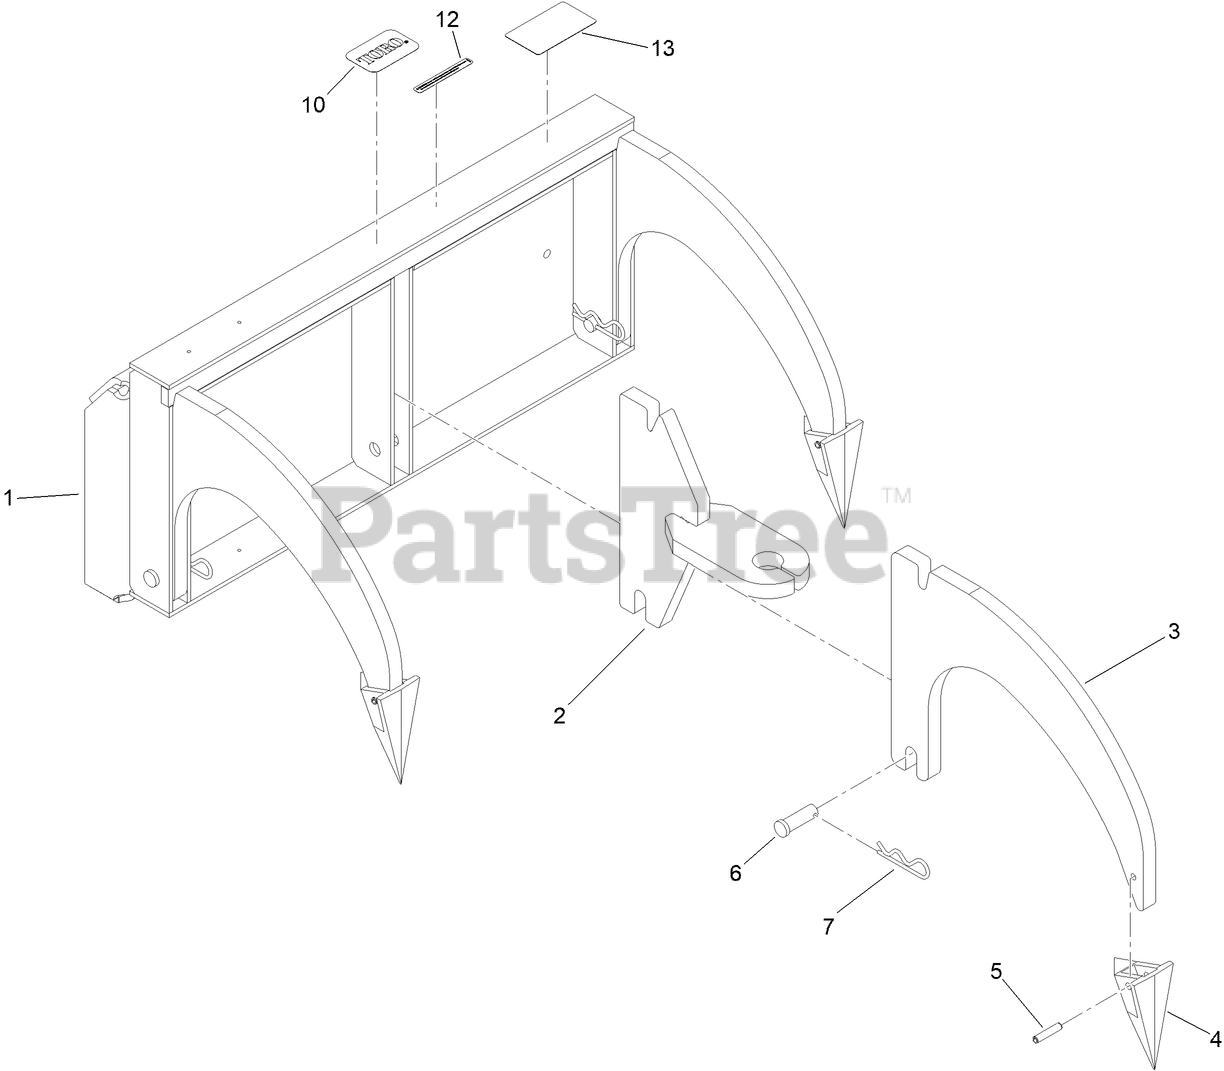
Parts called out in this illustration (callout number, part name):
1	CARRIER TOOL ASM
2	TOW BAR ASM
3	PLATE-TYNE
4	POINT-SPEAR
5	PIN-ROLL
6	PIN-CLEVIS
7	PIN-HAIR
10	DECAL
12	DECAL-WARNING
13	DECAL - BALL HITCH LIMIT
